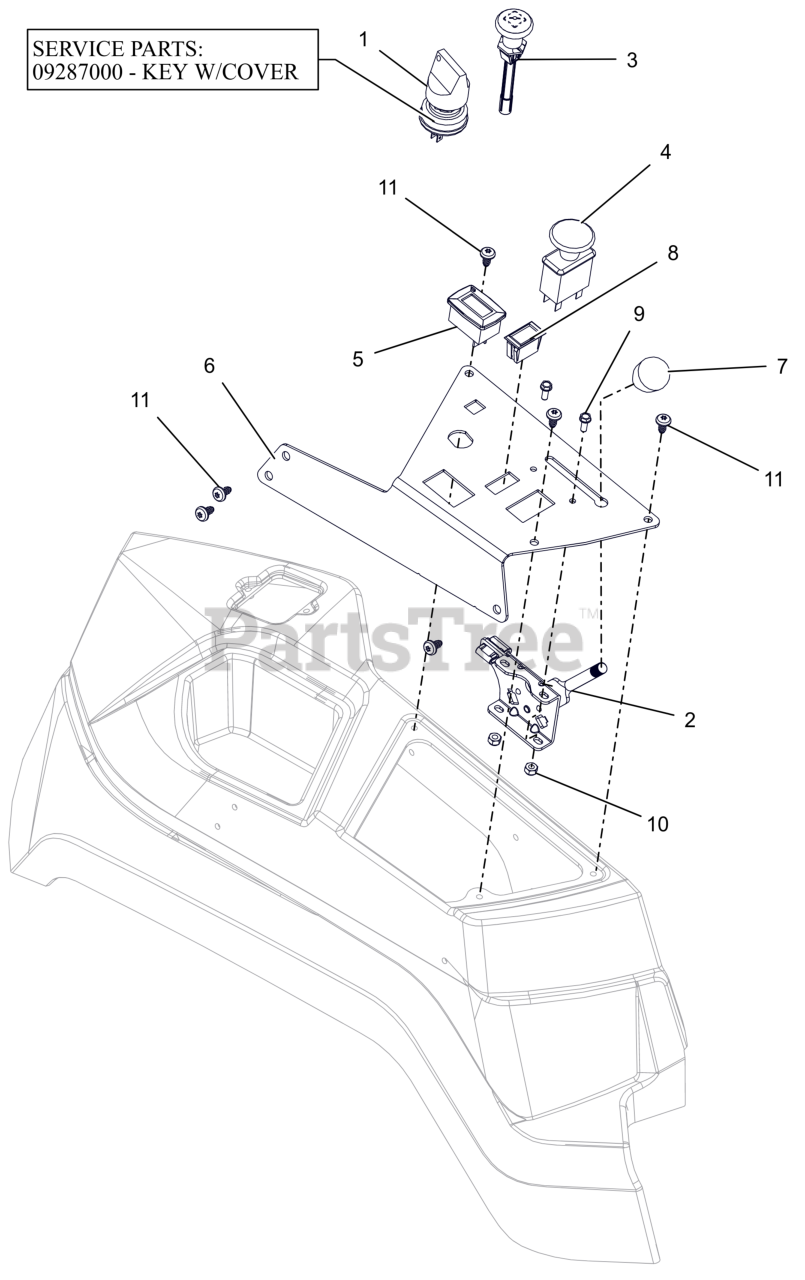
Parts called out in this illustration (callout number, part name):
1	SWITCH, IGNITION
1	KEY, W/ SHIELD
2	CABLE, PRO THROTTLE CONTROL
3	CABLE - CHOKE, SNAP-IN
4	SWITCH, CLUTCH
5	METER, HOUR W/MAINTENANCE
6	PLATE, APEX CONTROL PANEL
7	KNOB-CONTROL-BLACK .38-16X.50
8	SWITCH,BLANK
9	BLT, HWH #10-24X.50 ZCC
10	NUT-LK-NYL #10-24 G2 ZCC
11	SCR-PAN .25-15X.50 6L H/LZB500
